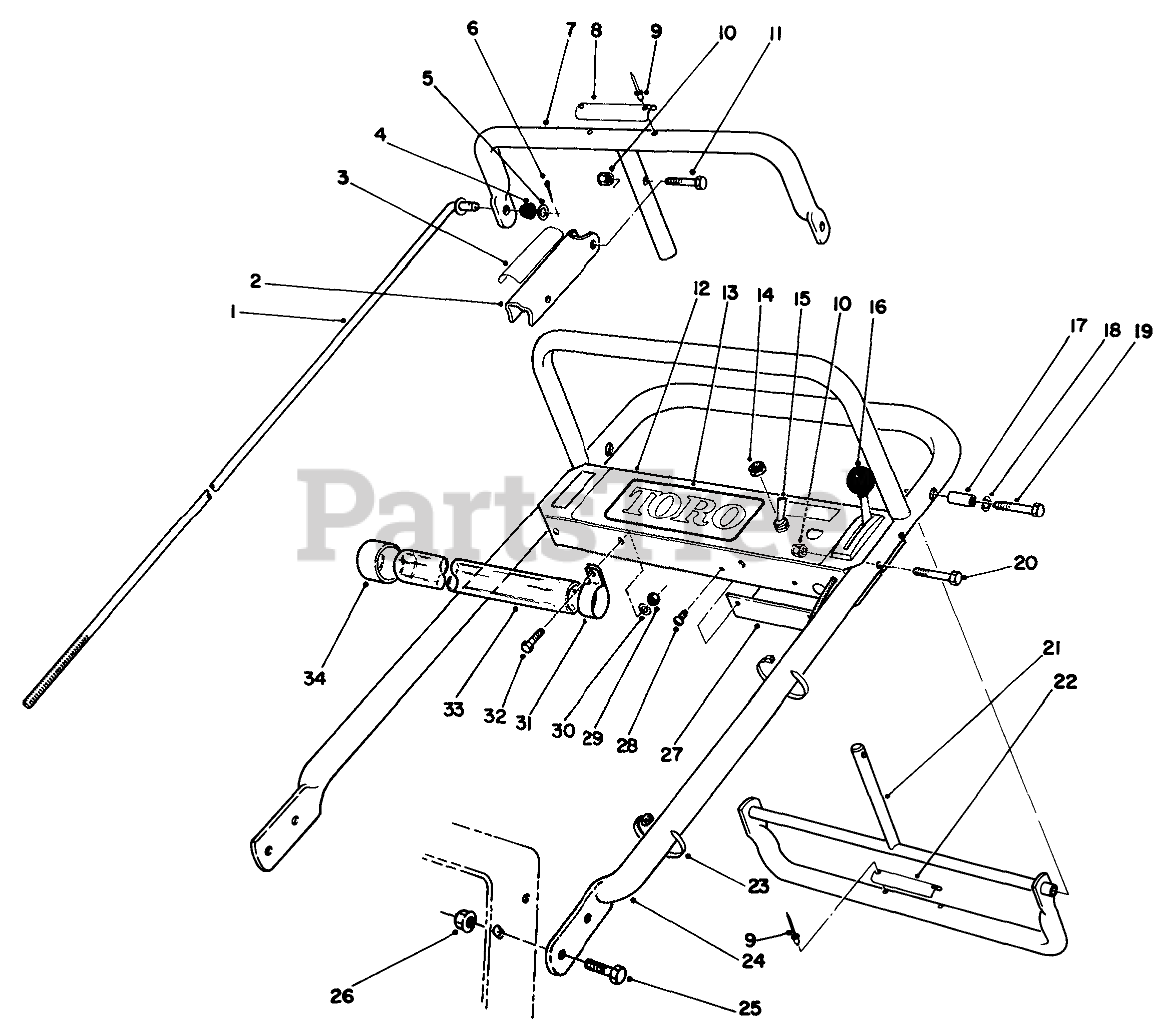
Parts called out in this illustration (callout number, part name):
1	ROD-CONTROL
2	Lever-Parking Brake
3	DECAL-LEVER, PARKING
4	GROMMET-RUBBER
5	WASHER-PLAIN
6	PIN-COTTER
7	Bar-Control
8	DECAL-CONTROL BAR
9	RIVET-BLIND
10	NUT-LOCK, NI
11	SCREW-SHH
12	Panel-Control
13	PANEL DECAL
14	NUT
15	Switch
16	THROTTLE-CONTROL
17	PIVOT-SPACER
18	WASHER-LOCK
19	SCREW-HH
20	SCREW-SHH
21	Control-Pivot
22	DECAL-REVERSE HANDLE
23	TIE-CABLE
24	HANDLE-UPPER
25	SCREW-HHF
26	NUT-HF
27	PANEL-BOTTOM
28	SCREW-HWHTF
29	NUT-LOCK, NI
30	WASHER-FLAT
31	CLAMP-R
32	SCREW-HH
34	CAP-END
